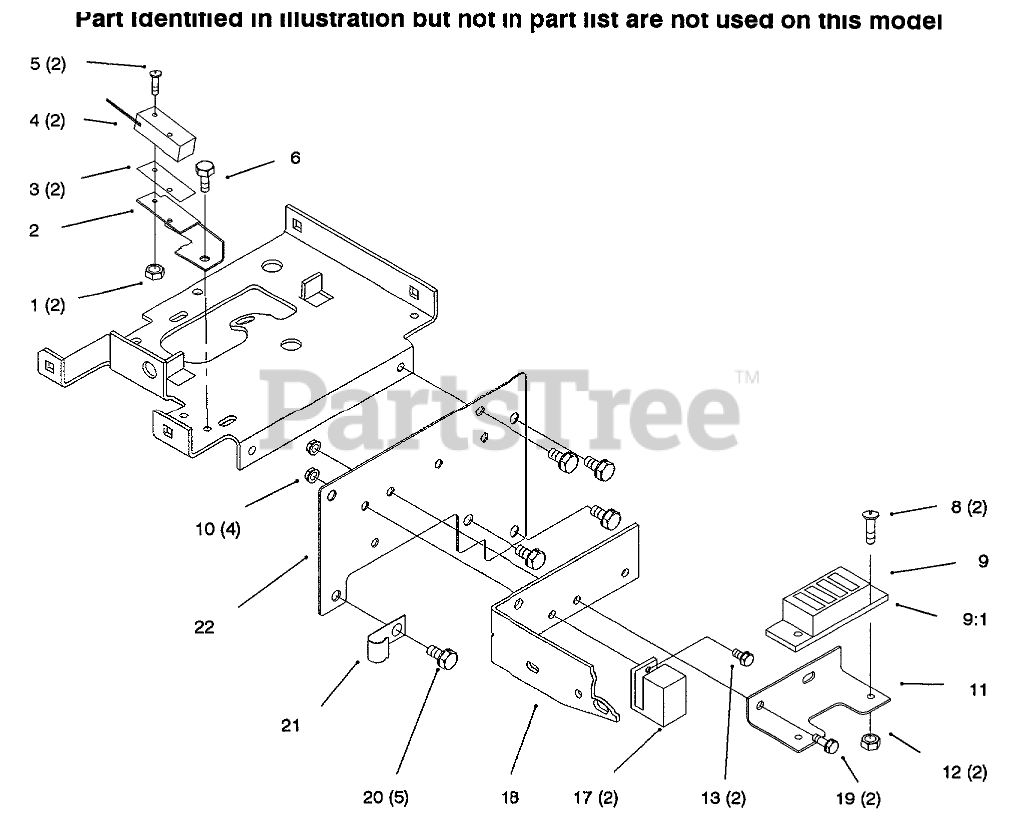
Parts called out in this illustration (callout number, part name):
1	NUT-HEX
2	BRACKET-SWITCH
3	BARRIER - SWITCH
4	SWITCH
5	SCREW-PHL 4-40X1 1/4
6	SCREW-HWH
8	SCREW-PAN
9	WIRING-HARNESS & DIA
9:1	FUSE-HOLDER 4 WAY
10	NUT-LOCK, NI
11	BRKT-FUS HLDERB
12	Nut
13	SCREW1/4-20X5/8 WHIZ
17	RELAY
18	BRACKET-BELTB
19	SCREW-HH
20	Bolt
21	CLIP
22	Front Plate
